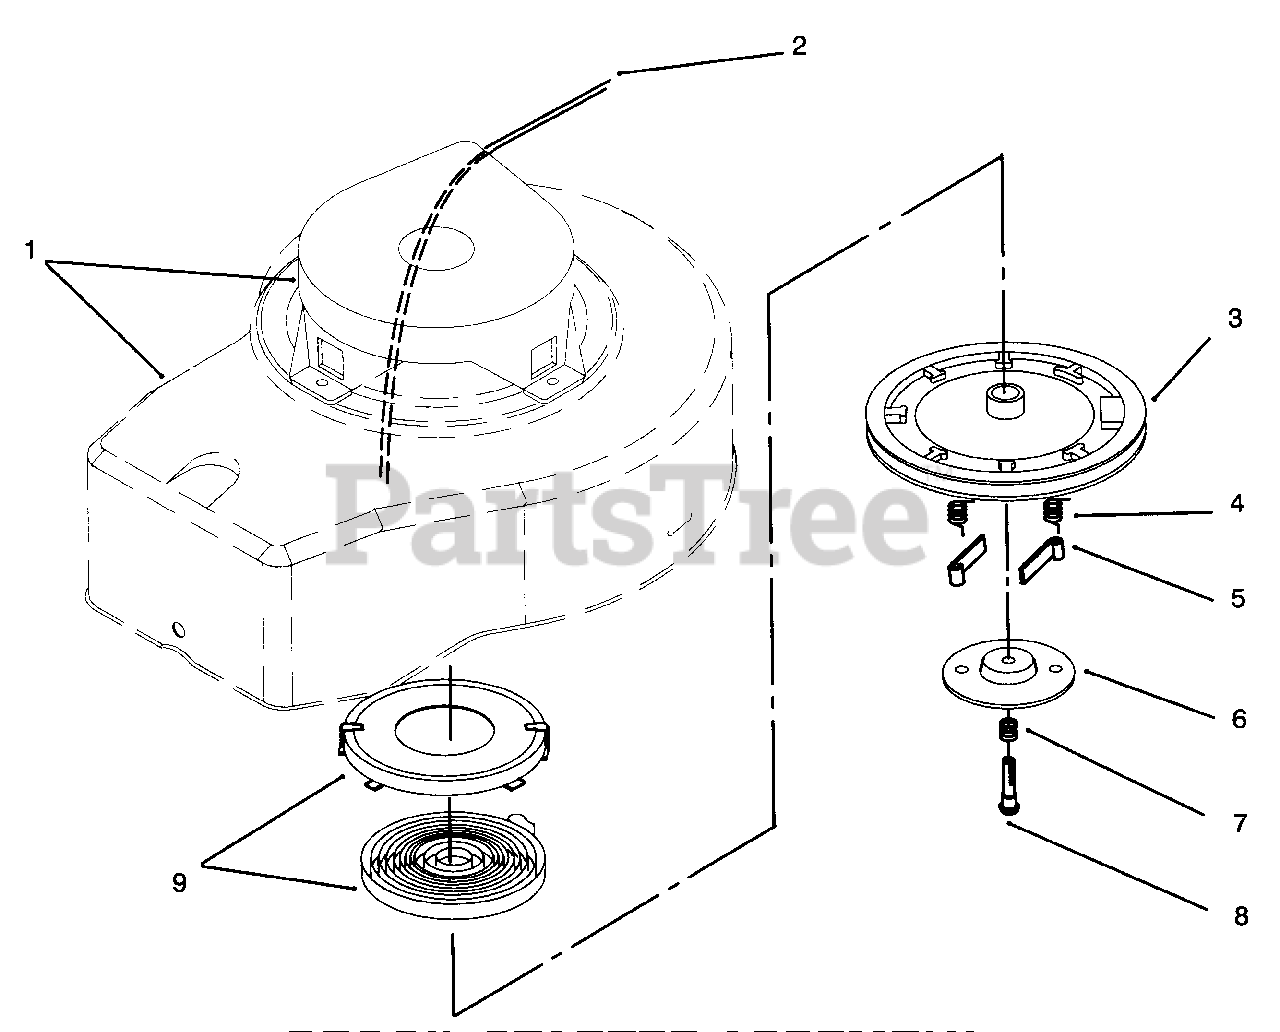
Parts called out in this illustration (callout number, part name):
1	Housing Assembly
2	Rope-Starter
3	Pulley Assembly
4	Spring-Dog
6	Retainer
9	Spring Keeper Assembly
